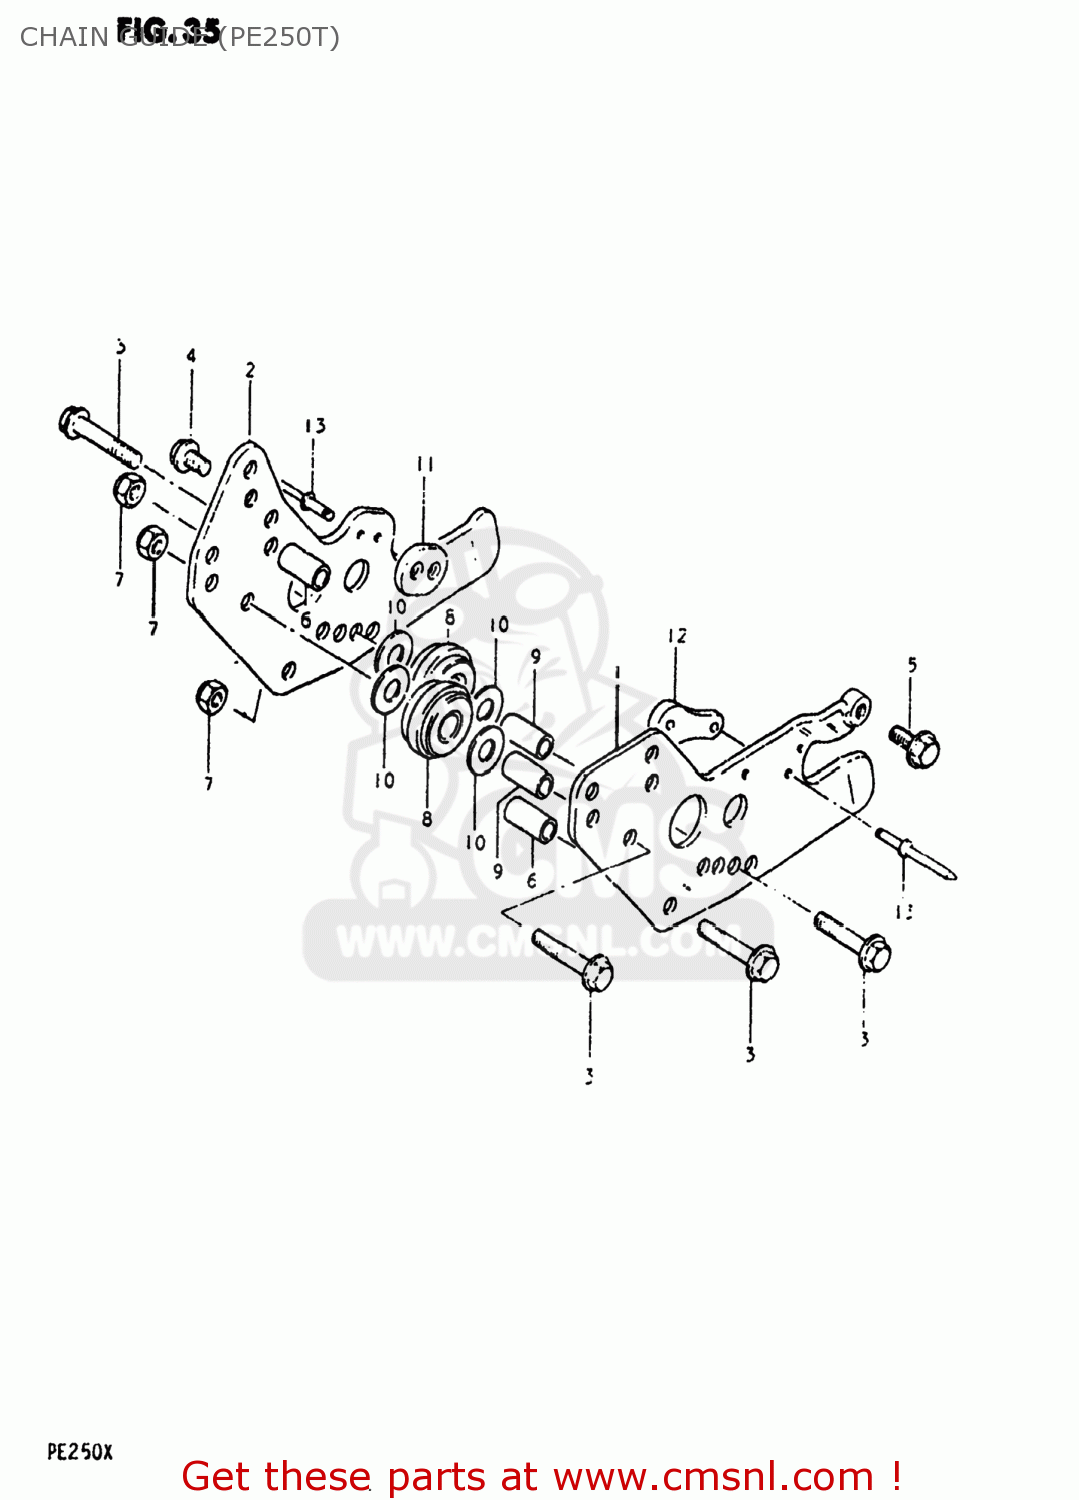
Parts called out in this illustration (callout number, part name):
1	PLATE,CHAIN GUIDE,OUTER
2	PLATE,GUIDE CHAIN
3	BOLT
4	BOLT
5	BOLT
6	SPACER(6.8X10X24.2)
7	NUT
8	ROLLER,CHAIN GUIDE
9	SPACER,CHAIN GUIDE ROLLER
10	WASHER
11	PAD,DRIVE CHAIN GUIDE
12	PAD,DRIVE CHAIN GUIDE
13	RIVET
